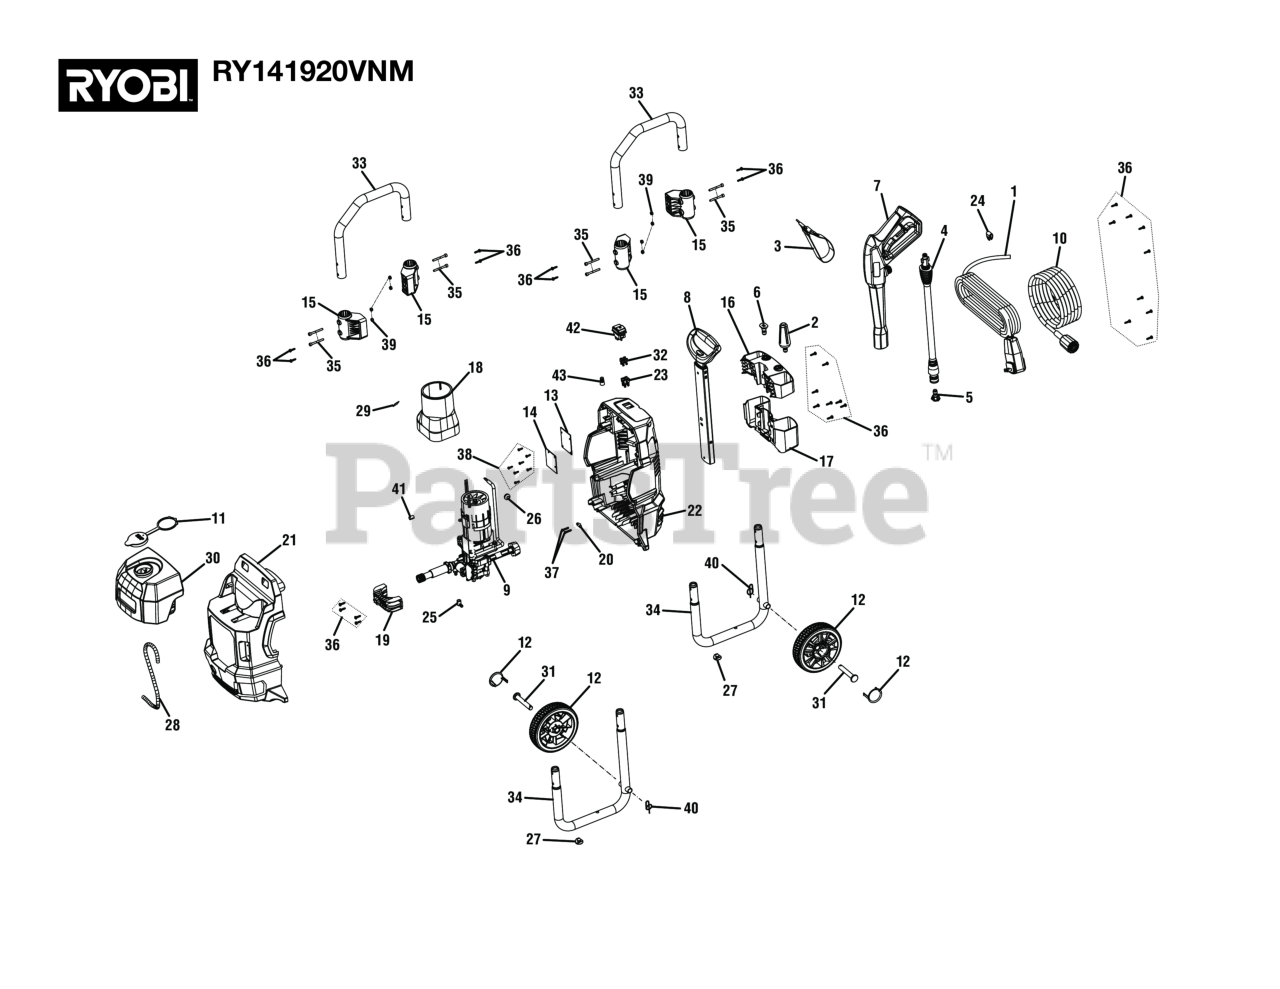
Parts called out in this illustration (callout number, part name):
1	Power Cord Assembly
2	Turbo Nozzle
3	Hose Storage Strap
4	Spray Wand Assembly
5	Nozzle (15deg)
6	Soap Nozzle (Blue)
7	Trigger Handle Assembly
8	Retractable Handle Assembly
10	25 ft. Hose
11	Detergent Tank Cap
12	Wheel Assembly
13	Switch Cover
14	Vent Cover
15	Frame Holder
16	Wand/Trigger Handle Holder
17	Wand/Trigger Handle Pocket
18	Air Shourd
19	Pump Bracket
20	Cord Clamp
21	Front Housing
22	Rear Housing
23	Plastic Sleeve (Terminal)
24	Electric Cord Clip
25	Soap Hose Inlet Adapter
26	Housing Rubber Grommet
27	Rubber Foot
28	Chemical Siphon Tube
30	Soap Tank
31	Wheel Axle
32	Tinned Brass (Terminal)
33	Upper Frame Tube
34	Lower Frame Tube
35	Bolt (M5 x 42 mm)
36	Screw (M4.2 x 15 mm, Phillips Hd. S.T.)
37	Screw (M3.5 x 20 mm, Button Hd.)
38	Screw (M3.5 x 12 mm, T15 Torx Pan Hd.)
39	Lock Nut (M5 x 0.8 mm)
40	Hitch Pin
41	Heat Shrinkable Tube
42	On/Off Switch
43	Tuerca para alambre
